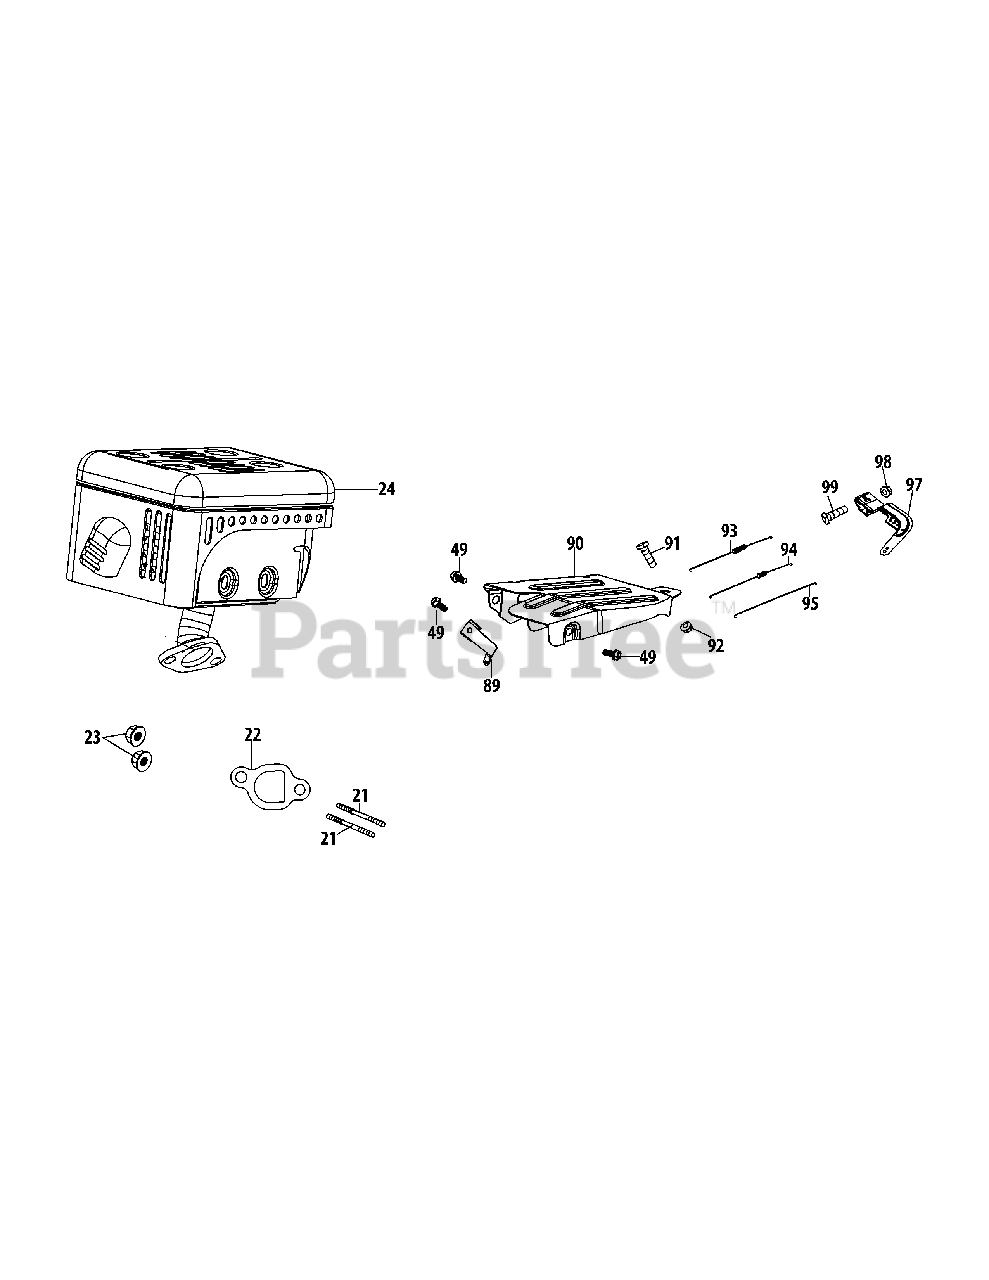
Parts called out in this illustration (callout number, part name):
21	Stud M8×36
21	Muffler Stud Assembly
22	Exhaust Pipe Gasket
24	Muffler Assembly
49	Bolt M6×12
89	Covernor Spring Bracket
90	Governor Shield
91	Bolt M6×28
93	Governor Spring
94	Throttle Linkage Spring
95	Throttle Linkage
97	Governor Arm
98	Nut M6
99	Governor Arm Bolt
